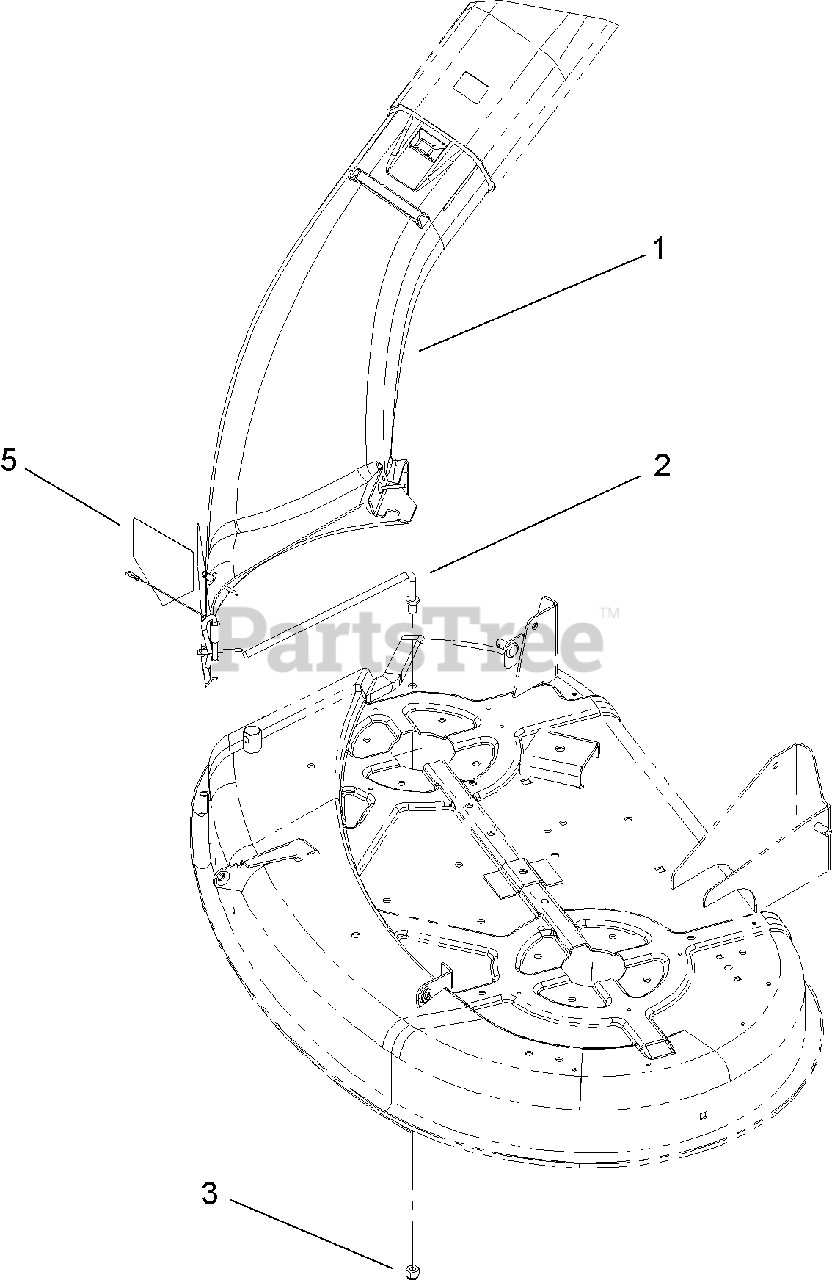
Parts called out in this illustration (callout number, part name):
1	BAGGER CHUTE ASM
2	ROD-PIVOT
3	NUT-LOCK, NI
5	DECAL-DANGER
